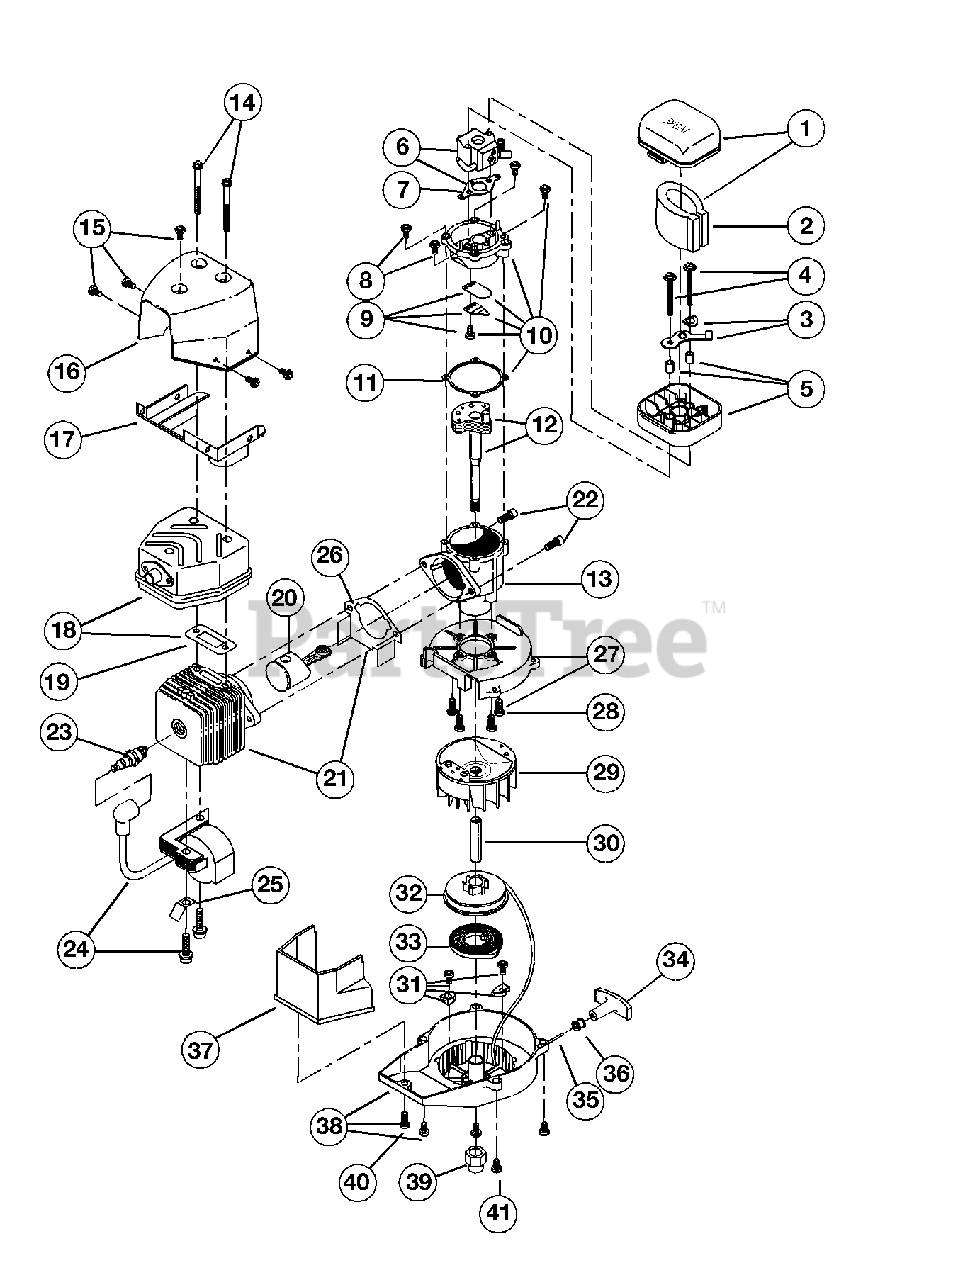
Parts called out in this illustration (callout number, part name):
1	Air Cleaner Cover Assembly
2	Air Cleaner Filter
3	Choke Lever Assembly
4	Mounting Bolt Assembly
5	Air Cleaner Base
6	Carburetor Assembly
7	Carburetor Gasket (10 pack)
8	Reed Plate Mounting Screw
9	Reed Assembly
10	Complete Reed Plate Assembly
11	Reed Plate Gasket
12	Crankshaft Assembly
13	Crankcase Service Assembly
14	Muffler Mounting Bolt
15	Mounting Screw Assembly
16	Upper Heat Shield
17	Lower Heat Shield
18	Muffler Assembly
19	Exhaust Gasket (10 pack)
20	Piston and Rod Assembly
21	Cylinder Assembly
22	Cylinder Bolt
23	Spark Plug
24	Module Assembly
25	Ground Tab
26	Cylinder Gasket
27	Shroud Assembly
28	Shroud Screw
29	Flywheel Assembly
31	Pulley Retainer Assembly
32	Recoil Pulley Assembly
33	Recoil Spring
34	Pull Handle
36	Rope Guide
37	Shroud Extension
38	Starter Housing Assembly
39	Crankshaft Extension
40	Shroud Extension Screw
41	Housing Screw
